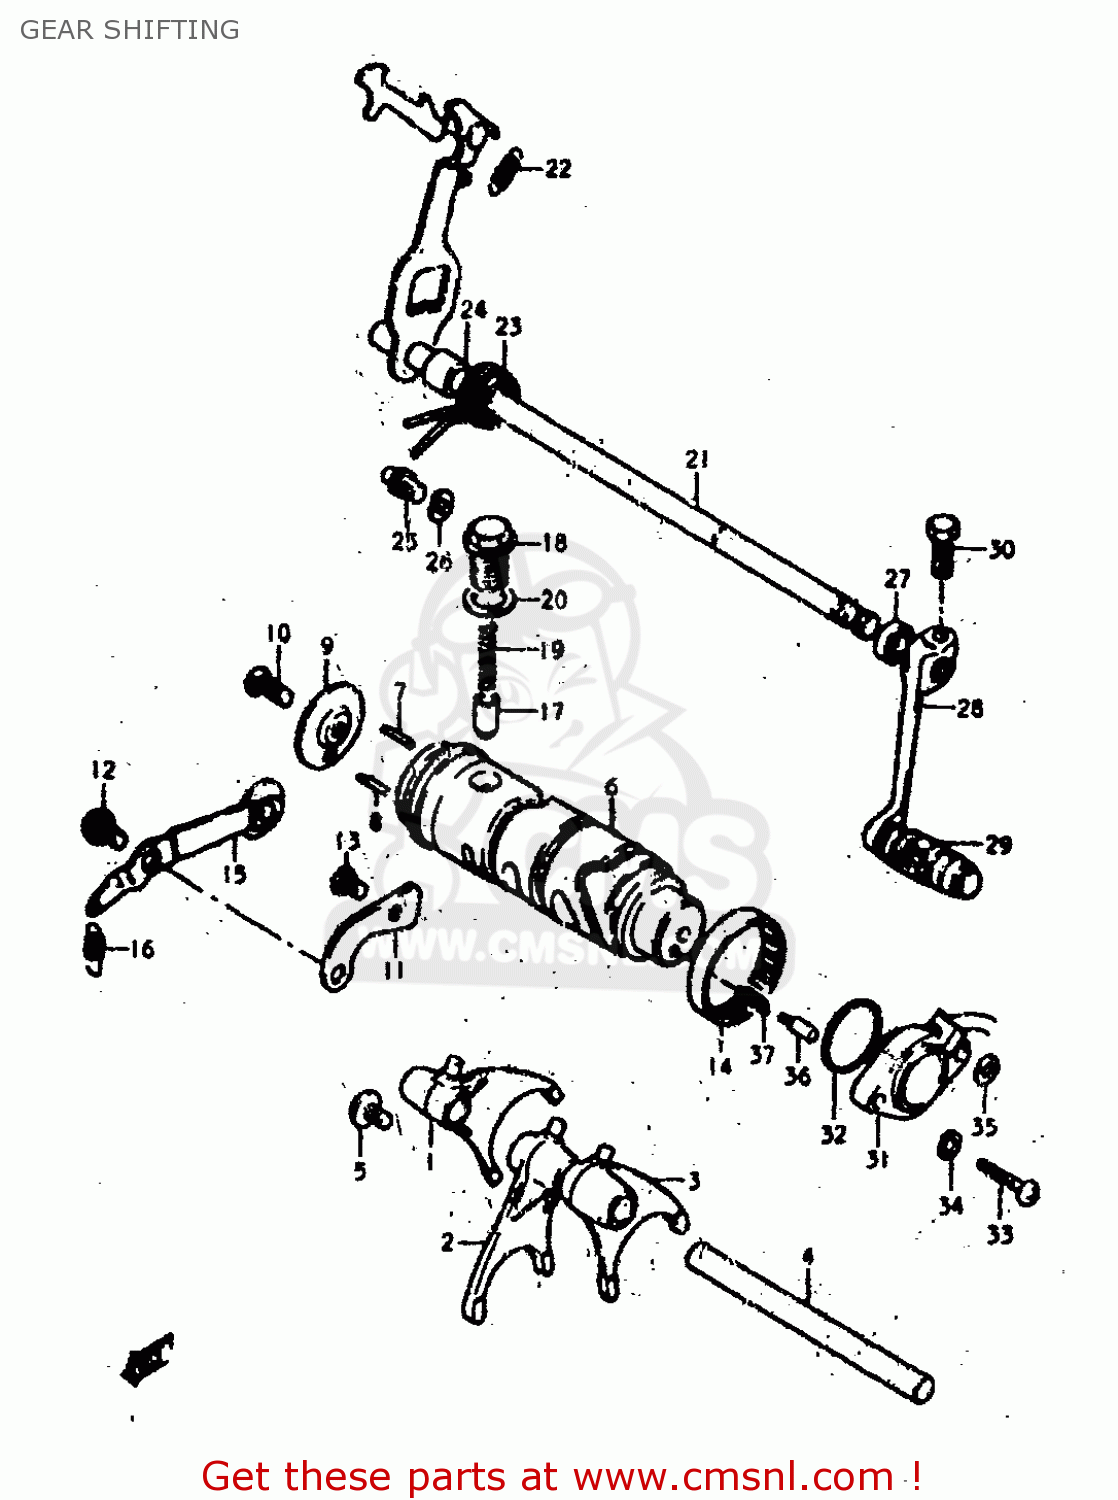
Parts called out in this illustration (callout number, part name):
1	FORK,GEAR SHIFT NO.1
2	FORK,GEAR SHIFT NO.2
3	FORK,GEAR SHIFT NO.2
4	SHAFT,GEAR SHIFT FORK
5	SCREW
6	CAM,GEAR SHIFT
7	PIN(4X18.5)
8	PIN
9	RETAINER,GEAR SHIFT CAM DR PIN
10	SCREW
11	GUIDE,GEAR SHIFTING CABLE
12	BOLT
13	BOLT
14	BEARING(40X47X12)
15	STOPPER,GEAR SHIFT CAM NO.1
16	SPRING
17	STOPPER,GEAR SHIFTING
18	BOLT,GEAR SHAFT CAM STOPPER
19	SPRING
20	GASKET(14X19.2X2) (NAS)
21	SHAFT,GEAR SHIFT
22	SPRING
23	SPRING
24	SPACER(12X20X15.3)
25	STOPPER
26	LOCK WASHER
27	OIL SEAL
28	LEVER ASSY,GEAR SHIFT
29	RUBBER,GEAR SHIFT PEDAL
30	BOLT
31	BASE ASSEMBLY,NEUTRAL SWITCH TERMINAL
32	O-RING (D:2.4 ID:26.2)
33	SCREW 5X20
34	LOCK WASHER
35	WASHER
36	PIN(5X15.5)
37	SPRING
